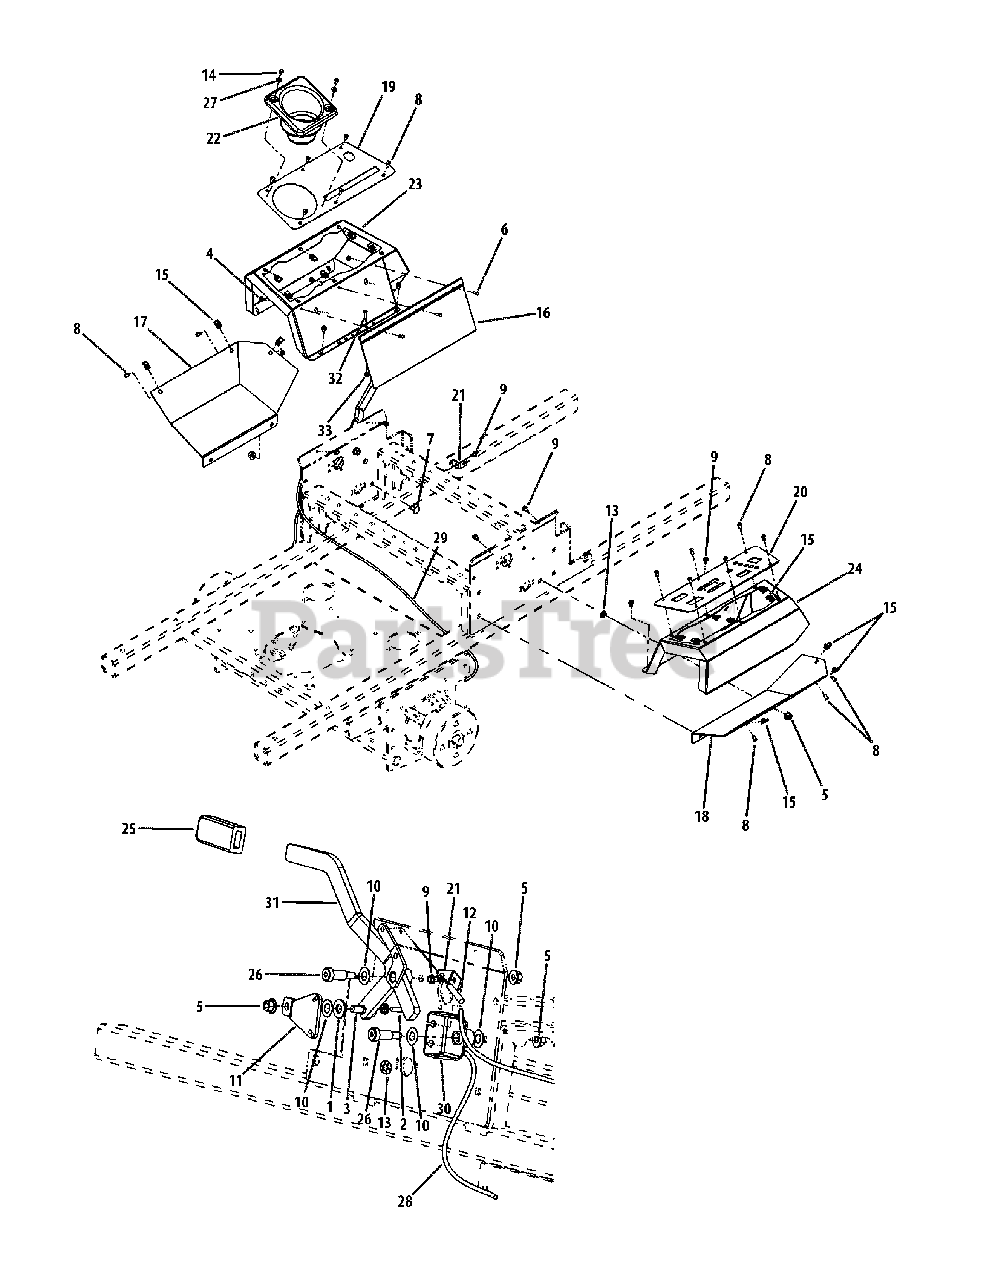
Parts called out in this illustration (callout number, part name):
1	Washer, 1/2 Zinc
2	Carriage Bolt, 3/8-16, 1.00
3	Shoulder Bolt, 1/2 x 1/2
4	Lock Nut, Nylon Insert, 10-32
5	Flange Lock Hex Nut, 3/8-16
6	Machine Screw, 10-32 x 5/8
7	Carriage Bolt, 3/8-16 x .75
8	Screw Button Head, 1/4-20 x .5
9	Screw, TT, 1/4-20, 0.5, Washer
10	Washer, .508 ID x 1.0 OD x .020
11	Centering Bracket
12	Left Hand Brake Cable
13	Push Retainer, 3/8
14	Screw, #10-32 x 0.500
15	U-Nut, 1/4-20
16	Bag, Debris Storage
17	Lower Panel, LH
18	Lower Panel, RH
19	Control Panel Cover, LH
20	Control Panel Cover, RH
21	Brake Cable Mounting Bracket
22	Cup Holder
23	Control Panel, LH
24	Control Panel, RH
25	Parking Brake Grip
26	Shoulder Bolt, 1/2 x 1.00, 3/8-16
27	Washer, 3/16
28	Brake Cable, LH
29	Brake Cable, RH
30	Brake Cable Bracket
32	Screw, Hex, Cap, 1/4-20 x .75
33	Lock Nut, 1/4-20
